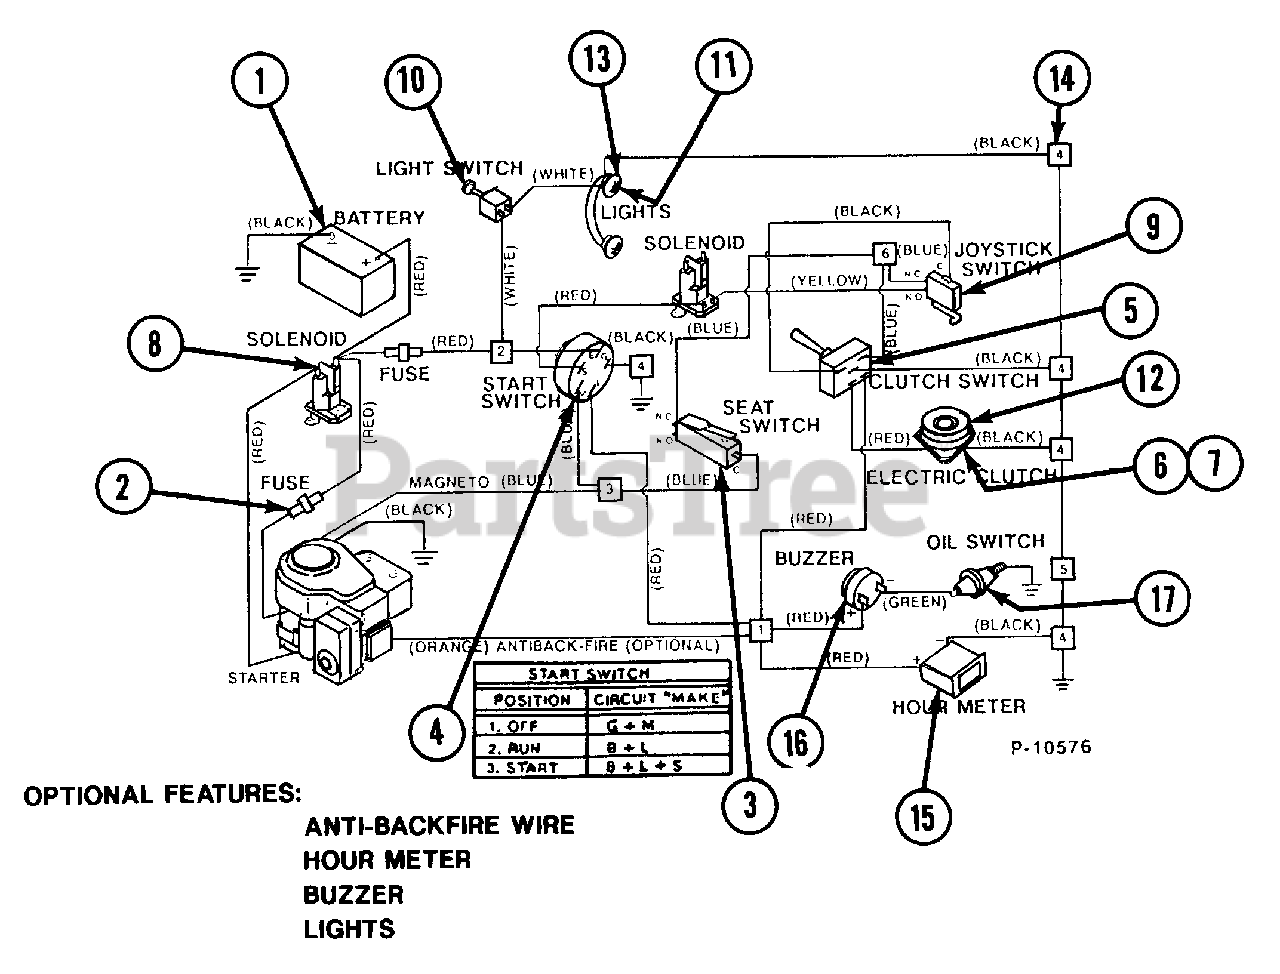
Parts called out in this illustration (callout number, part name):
1	BATTERY
2	FUSEHOLDER (INLINE)
3	SEAT SWITCH
4	START SWITCH
5	CLUTCH SWITCH
6	TERMINAL
7	INSULATOR COVER
8	SOLENOID
9	NEUTRAL SWITCH
10	HEADLIGHT SWITCH
11	HEADLIGHT
12	ELECTRIC CLUTCH
13	HEADLIGHT MOUNTING RING
14	6 POINT TERMINAL BOARD
15	HOUR METER
16	BUZZER
17	OIL PRESSURE SWITCH
